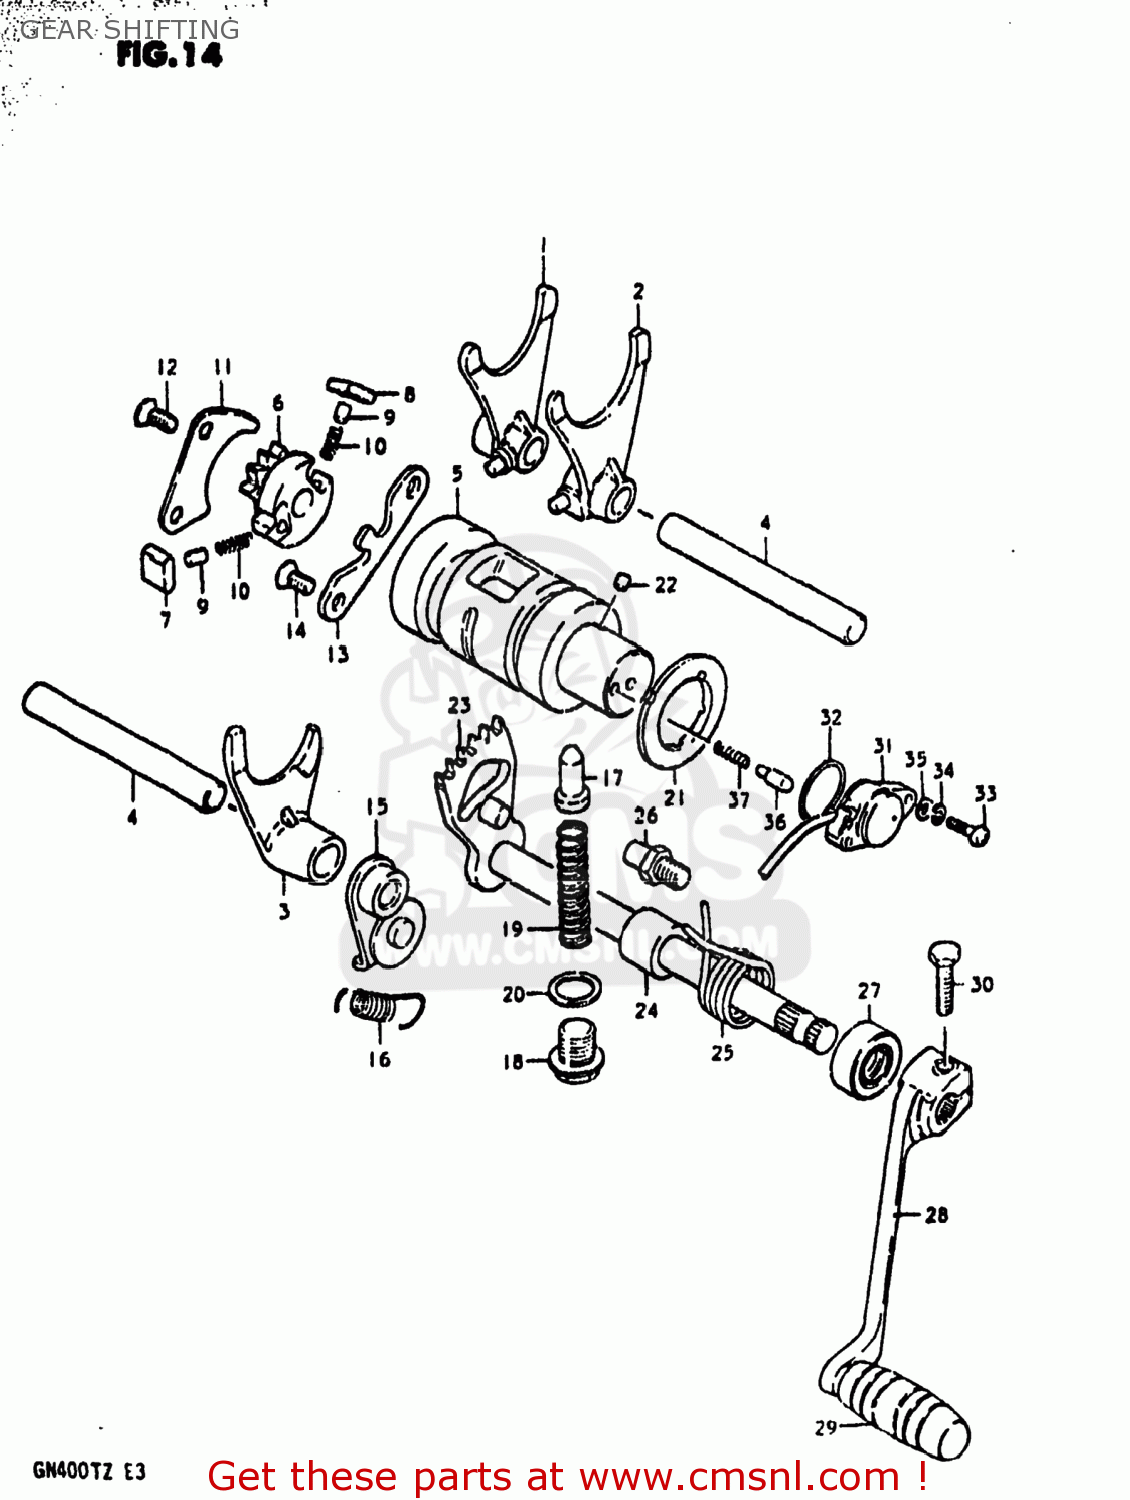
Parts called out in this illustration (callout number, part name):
1	FORK,GEAR SHIFT NO.1
2	FORK,GEAR SHIFT
3	FORK,GEAR SHIFT NO.3
4	SHAFT,GEAR SHIFT FORK
5	CAM,GEAR SHIFT
6	RETAINER,GEAR SHIFT CAM
7	PAWL,GEAR SHIFT NO.1
8	PAWL,GEAR SHIFT NO.2
9	PIN(5X8)
10	SPRING
11	LIFTER,GEAR SHIFT PAWL
12	SCREW
13	GUIDE,GEAR SHIFT CAM
14	SCREW
15	STOPPER,GEAR SHIFT CAM
16	SPRING
17	STOPPER,GEAR SHIFT CAM NO.2
18	PLUG (14X12)
19	SPRING
20	GASKET(14X19.2X2) (NAS)
21	PLATE,GEAR SHIFT CAM STOPPER
22	PIN 4X6
23	SHAFT,GEAR SHIFT
24	SPACER(12X20X15.3)
25	SPRING
26	STOPPER,GEAR SHIFT CAM
27	OIL SEAL
28	LEVER ASSEMBLY,GEAR SHIFTING
29	RUBBER,GEAR SHIFT PEDAL
30	BOLT
31	TERMINAL BASE ASSY,GEAR SHIFT
32	O-RING (D:2.4 ID:26.2)
33	SCREW 5X20
34	LOCK WASHER
35	WASHER
36	PIN(5X15.5)
37	SPRING
